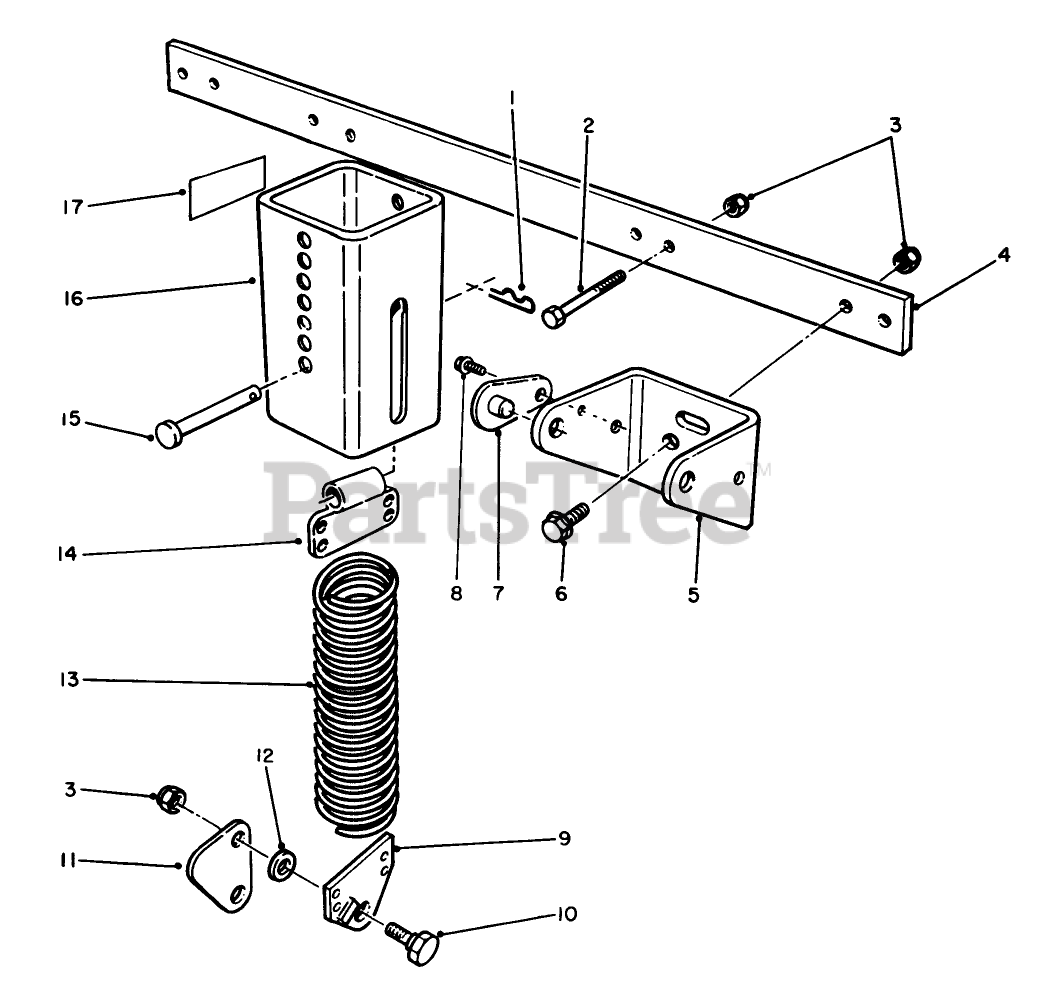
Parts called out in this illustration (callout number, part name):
1	PIN-HAIR
2	SCREW-HH
3	NUT-LOCK, NI
4	Adapter
5	Bracket-Support
6	SCREW-HHF
7	PIN-LOCK
8	SCREW
9	End Spring
10	BOLT-SHOULDER
11	Link
12	WASHER-FLAT
13	Spring-Extension
14	End Spring
15	PIN-CLEVIS
16	Asm-Spring Cover
17	DECAL-WARNING
